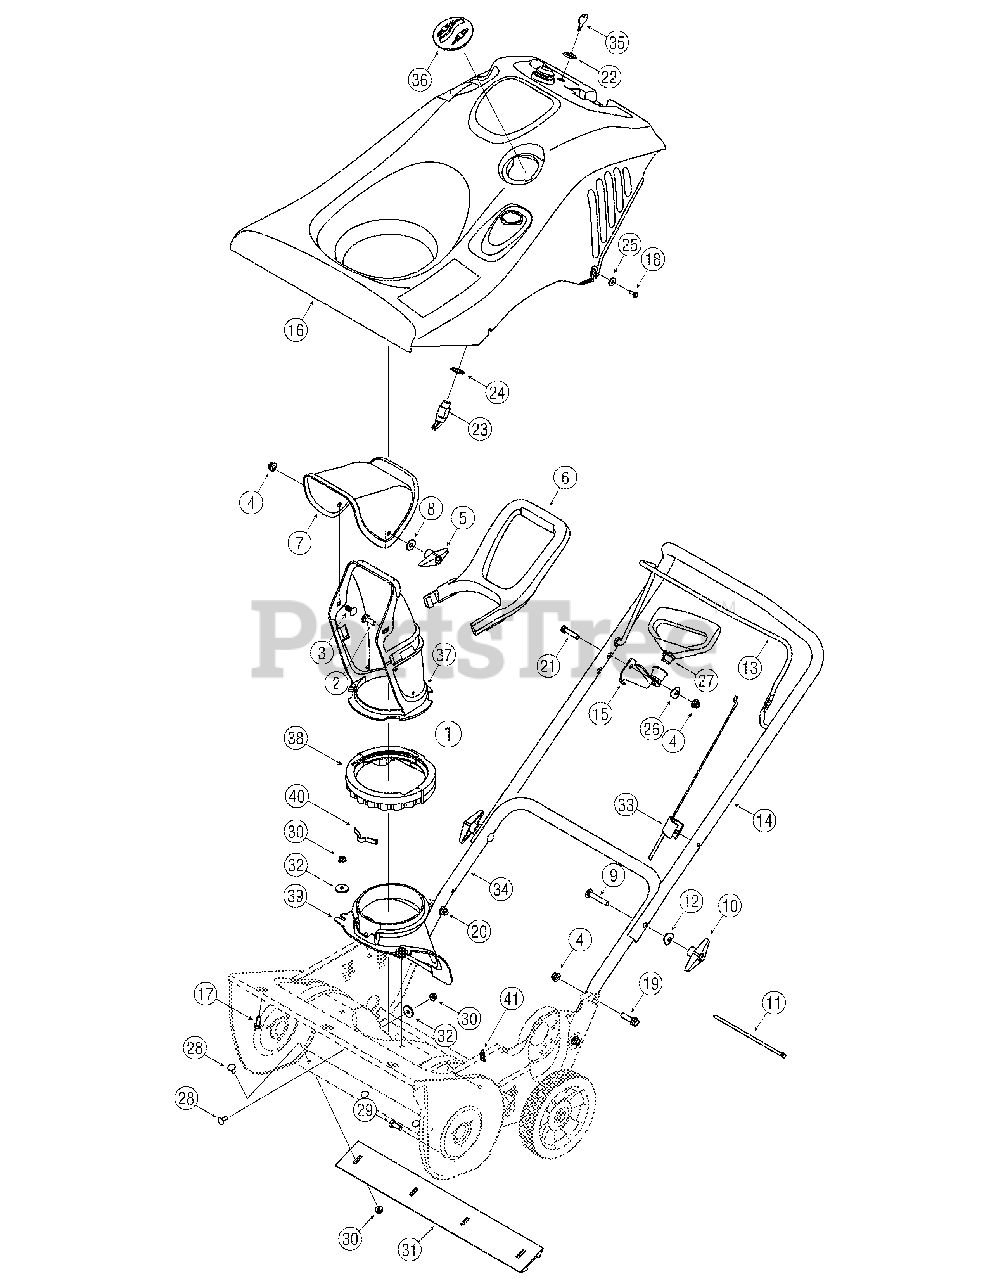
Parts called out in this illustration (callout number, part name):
1	Chute Assembly
2	Carriage Bolt 5/16-18 x 1.0"
3	Carriage Bolt 5/16-18 x 0.750"
4	Flange Lock Nut, 5/16-18
5	Chute Knob Assembly
6	Chute Handle
7	Upper Chute
9	Carriage Bolt 5/16-18 x 2.0 Gr. 1
10	Handle Knob Assembly 5/16-18
11	Cable Tie
12	Saddle Washer .320 x .93
15	Mitten Grip Bracket
16	Shroud Assembly, Black (Incl. Spark Plug Cover)
17	Screw, 1/4-15 x .75
18	Self-tapping Screw, #10-16 x .625"
19	Hex Flange Screw, 5/16-18 x 1.25
20	Hex Flange Screw 5/16-18 x 1.50 Gr. 5
21	Hex Screw, 5/16-18 x 1.375
22	Hex Nut 5/8-32 x .12 Special
23	Key Switch-Electric Start
24	Lock Washer Internal .625 x 1.058
25	Flat Washer .194" x .62" x .063
26	Saddle Washer .320 x .93
27	Recoil Handle, Mitten
28	Screw, 1/4-20 x .62
29	Truss Machine Screw, 5/16-18 x .75
30	Hex Flange Lock Nut, 1/4-20
31	Shave Plate, 19.88
32	Flat Washer .265 x .938 x .120
33	Control Cable
35	Ignition Key
36	Spark Plug Cover
37	Lower Chute 5" Dia.
38	Ring-Lower Chute
39	Chute, Adapter 5" Dia
40	Chute Adjustment Spring
41	Extension Spring
